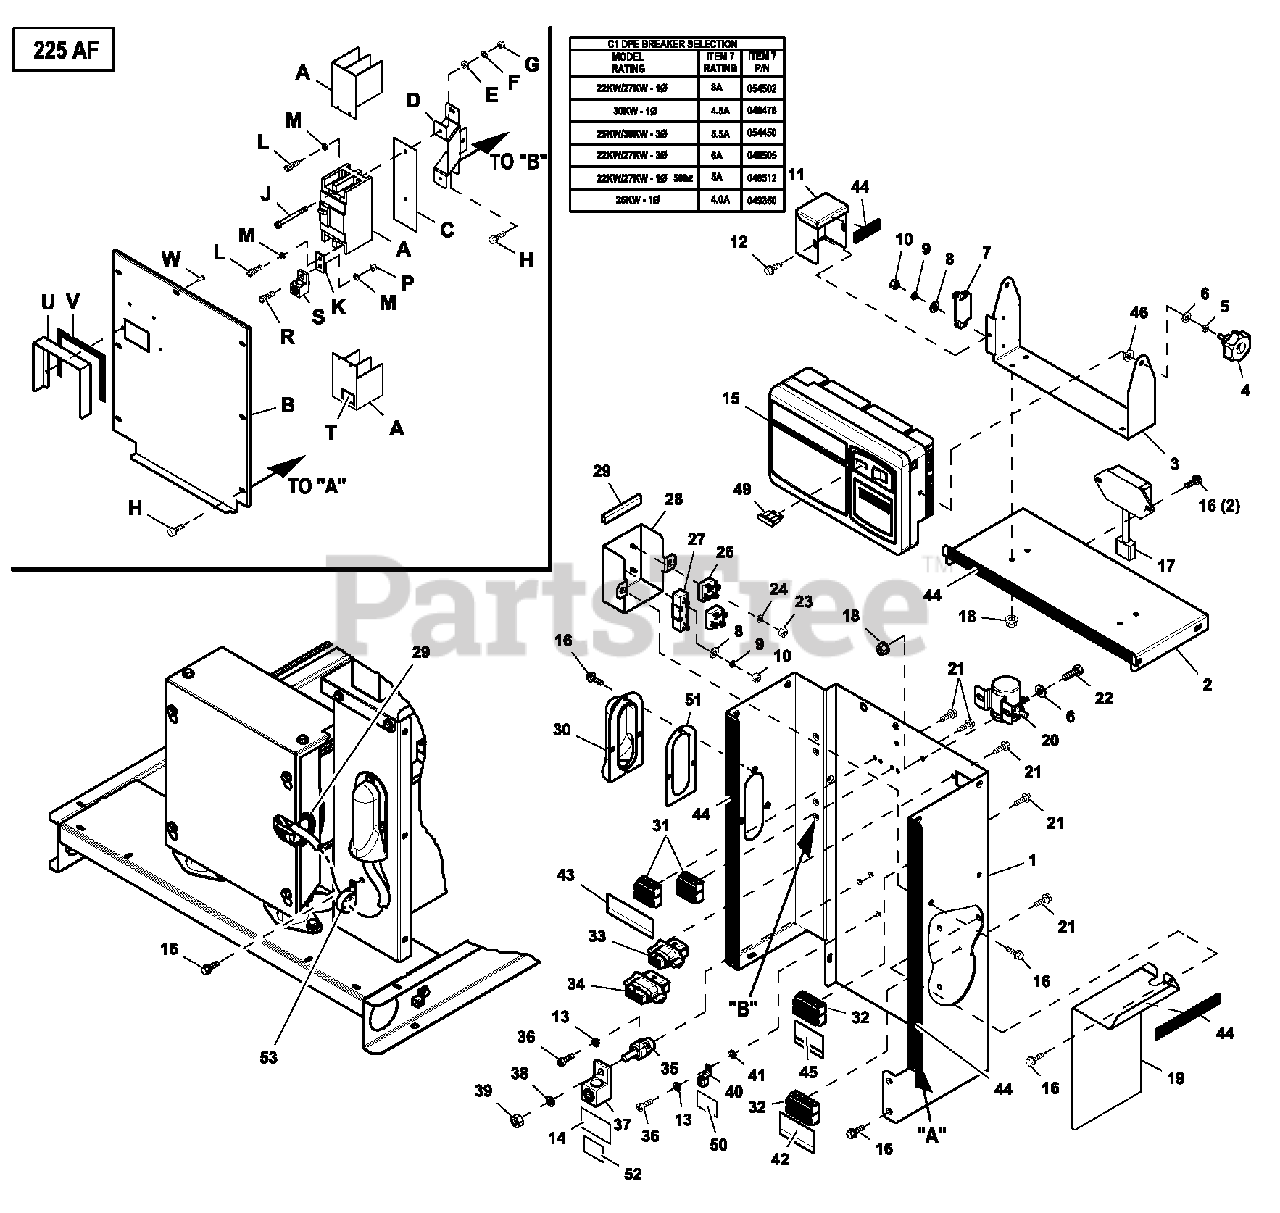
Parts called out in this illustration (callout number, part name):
1	CONBOX BACK/SIDES C1 CPL
2	CONBOXTOP C1 CPL
3	BRACKET GIMBAL CONTROL PNL RAW
4	KNOB M6-1.0 CONTROL PANEL
5	WASHER LOCK M6-1/4
6	WASHER FLAT 1/4-M6 ZINC
7	CIRCUIT BREAKER
8	WASHER FLAT M3
9	WASHER LOCK M3
10	NUT HEX M3-0.5 G8 CLEAR ZINC
11	COVER DPE BREAKER NEXUS
12	SCREW HHTT M4-0.7 X 8 ZP
13	WASHER LOCK#8-M4
14	DECAL NEUTRAL
15	ASSY CTRL PROGRAMMED
16	SCREW HWHT M6-1 X 16 N WA Z/JS
17	REGULATOR-DC ALT
18	NUT FLANGE M6-1.0 NYLOK
19	SHIELD HIGH/LOW C1 RAW
20	RELAY SOLENOID 12VDC PNL MNT
21	SCREW HHSP #10 X 3/8 HI-LOW
22	SCREW HHC M6-1.0 X 20 C8.8
23	NUT HEX M5-0.8 G8 CLEAR ZINC
24	WASHER LOCK M5
26	DIODE BRIDGE 1P 35A 1000V
27	RES WW 15R 5% 25W QK CONN
28	COVER VOLTAGE SHIELD
29	TRIM VINYL BLACK 1/8GP (3"LG)
30	COVER BELL HOUSING CONBOX
31	TERM BLOCK 3P UL 12-20AWG
32	TERM BLOCK 4P UL 12-20AWG
33	MX150L SLRRMNT 22-18 8P W/O GA
34	MX150L SLRRMNT 22-18 12P W/OGA
35	JUNCTION BLOCK 3/8-16
36	SCREW PHTT M4-0.7 X 12 ZP
37	LUG SLDLSS 350-#6X13/32 AL/CU
38	WASHER LOCK 3/8
39	NUT HEX 3/8-16 STEEL
40	LUG SLDLSS #6-14 X 13/64 CU
41	WASHER LOCK EXT #10 STL
42	DECAL CUSTOMER CONTROL CONNECT
43	DECAL CONBOX TB1 CONNECTIONS
44	TAPE ELEC 1/2 FOAM (62" LG)
45	DECAL CUSTOMER POWER CONNECT
46	WASHER NYLON .257
49	FUSE ATO TYPE 7.5AMP (BROWN)
50	DECAL GROUND LUG
51	GASKET WIRE ENTRY COVER
52	DECAL CAUTION ELEC SHOCK SM
53	HOSE CLAMP
A	CB 150A 2 POLE 240V 225AF
B	COVER CB G 225AF C1 CONBOX
C	INSULATOR CB 2P 225AF
D	SPRT CIRCUIT BREAKER G 225AF
E	WASHER FLAT #8 ZINC
F	WASHER LOCK#8-M4
G	NUT HEX #8-32 STEEL
H	SCREW HWHT M6-1 X 16 N WA Z/JS
J	SCREW RHM #8-3 2X3 -1 /4
K	BUS BAR 200A LUG ADAPTOR
L	SCREW SHC M8-1.25 X 20 G8
M	WASHER LOCK M8-5/16
P	NUT HEX M8-1.25 G8 CLEAR Z I NC
R	SCREW HHC M8-1.25 X 25 C8.8
S	LUG SLDLSS 300 MCM-6 AL/CU
T	DECAL TERM I NAL SHOCK HZD B I
U	SH I ELD CB HANDLE CONBOX
V	TAPE ELEC 1/2 FOAM
W	R I VET POP .125 X .275 SS
